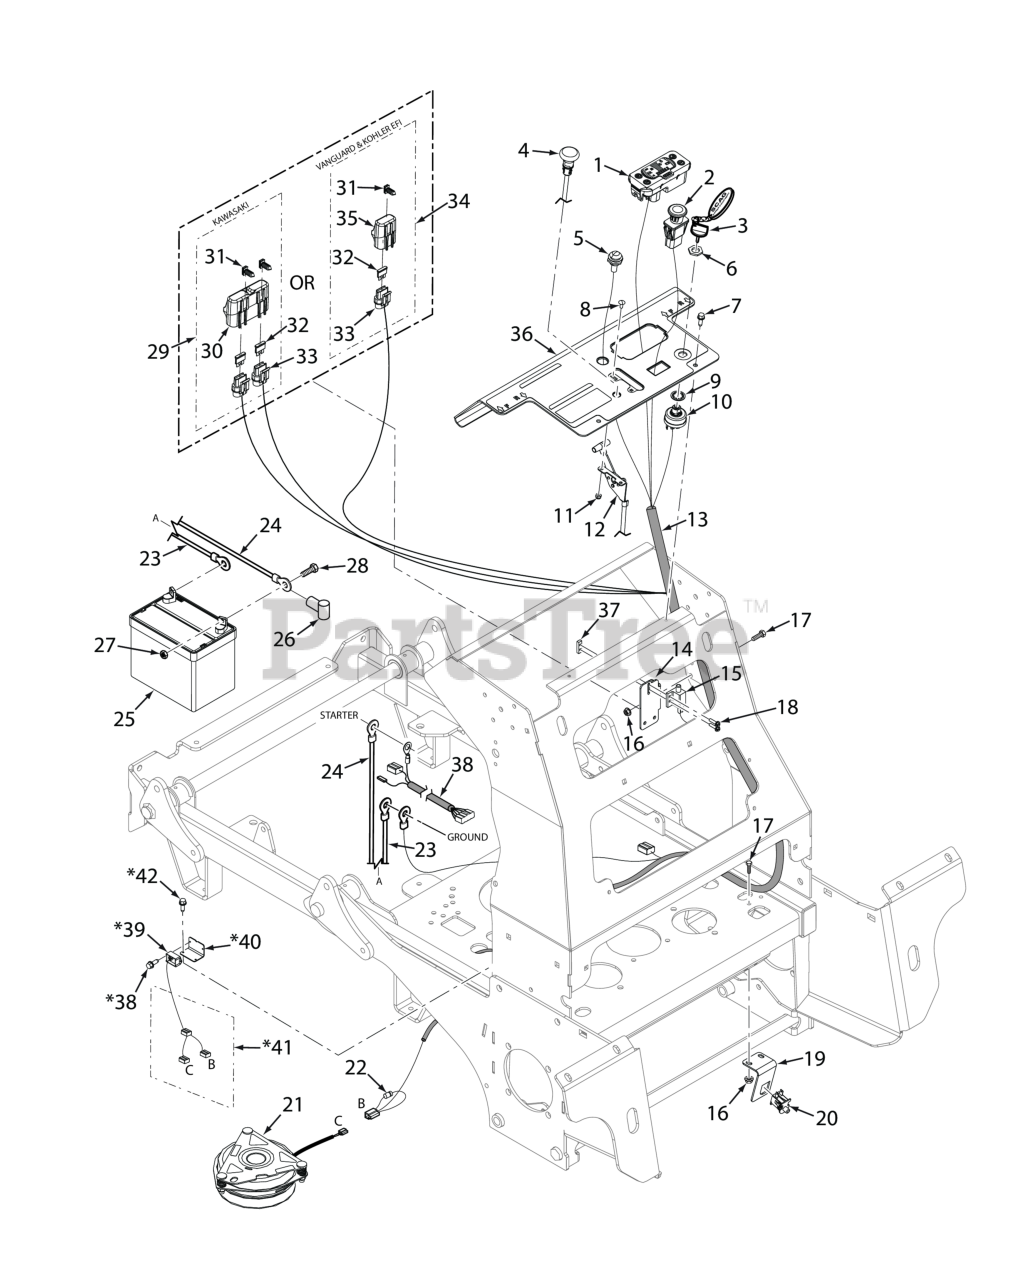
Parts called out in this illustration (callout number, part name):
1	Tiger Eye, Cluster Gauge
2	Switch, PTO - 10 Amp
3	Key, Assembly w/Fob
4	Choke Control (excludes EFI models)
5	Indicator Light, Glow Plugs (Includes Mounting Hardware)
6	Nut, 5/8-32 Special
7	Screw, Self-Tapping 1/4-20 x 3/4
8	Bolt, Carriage #10-24 x 1/2"
9	LOCK WASHER, 5/8" INTERNAL TOOTH
10	KEY SWITCH(INCLUDES MOUNTING HARDWARE)
11	Nut, Elastic Stop #10-24
12	Throttle Control, SVR
13	Wire Harness, SVRII
14	Bracket, Neutral Switch
15	Switch, Interlock, Park Brake Normally Open
16	NUT, 1/4-20 SERRATED FLANGE HEX HEAD
17	BOLT, HEX HEAD, 1/4-20 X 3/4 GR.5
18	Screw, Hex-Slotted Washer Head #10 32 x 3/4"
19	Switch Bracket, Operator Presence
20	SWITCH, NEUTRAL INTERLOCK
21	Clutch w/Tag GT2.5-FE02 (48 / 52)
22	Diode, 600V 6 Amp
23	Battery Cable, 39" Black (26EFI) - Kohler
24	Battery Cable, 44" Red w/Braid (26EFI) - Kohler
25	Battery, 350 CCA (not available through Scag)
26	RUBBER BOOT
27	Nut, 1/4 - 20 Hex
28	BOLT, HEX HEAD, 1/4-20 X 3/4 GR.5
29	Double Fuse Assy.
30	Cover, Sealed Double
31	Clip, Fuse Holder
32	FUSE, 20 AMP BLADE TYPE AUTOMOTIVE
33	Fuse Holder Assembly
34	Single Fuse Assy., Excluding Fuse
35	Cover, Sealed Single
36	Control Panel with Decal
37	Plate, Threaded
39	Soft Start Module, Clutch
40	Mounting Bracket, Soft Start Module
41	Wire Harness, Clutch Soft Start
42	Screw, #10-32 x .563 Shakeproof
